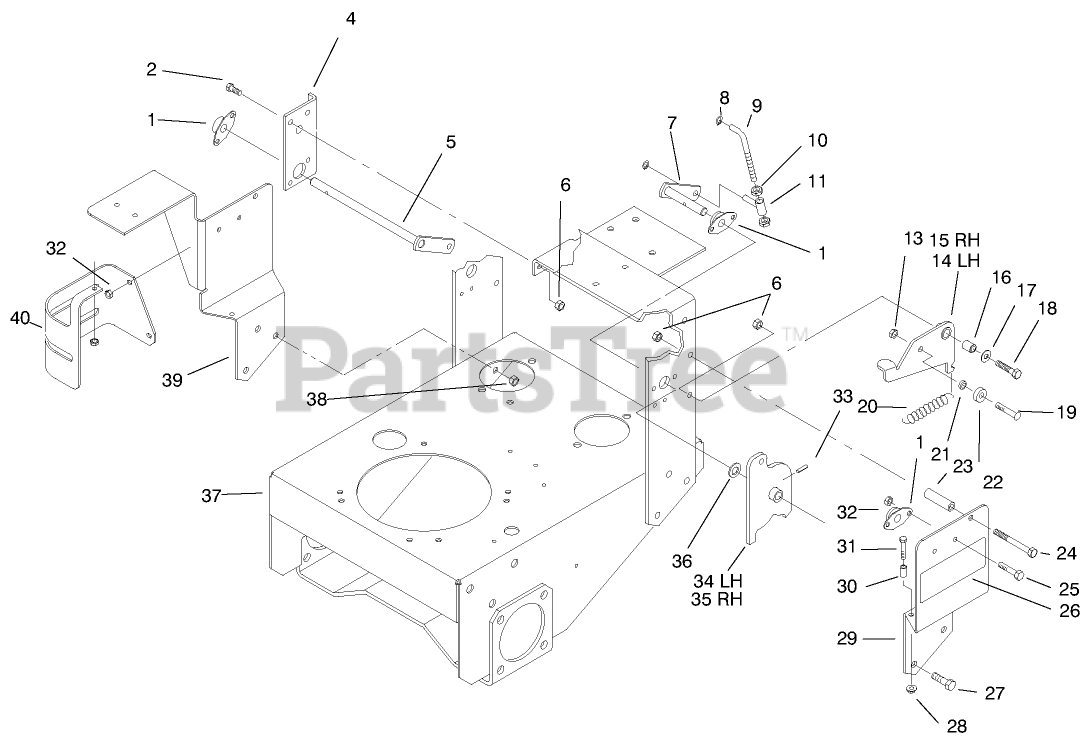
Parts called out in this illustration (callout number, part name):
1	CUSHION-RUBBER
2	NUT-HEX
3	FORK-CASTER, FRONT
4	CASTOR WHEEL ASM
5	SUSPENSION ASM
6	PIN-LYNCH
7	DECAL-HOC, LH
8	SCREW-HH
11	WASHER-THRUST
12	WASHER-FLAT
13	NUT-LOCK, SIDE
14	SHIM-CARRIER
15	SCREW-HHF
16	SCREW-HH
17	WASHER-FLAT
18	DECAL-HOC, RH
19	SPANNER-TIRE
20	FITTING-GREASE
21	BUSHING
